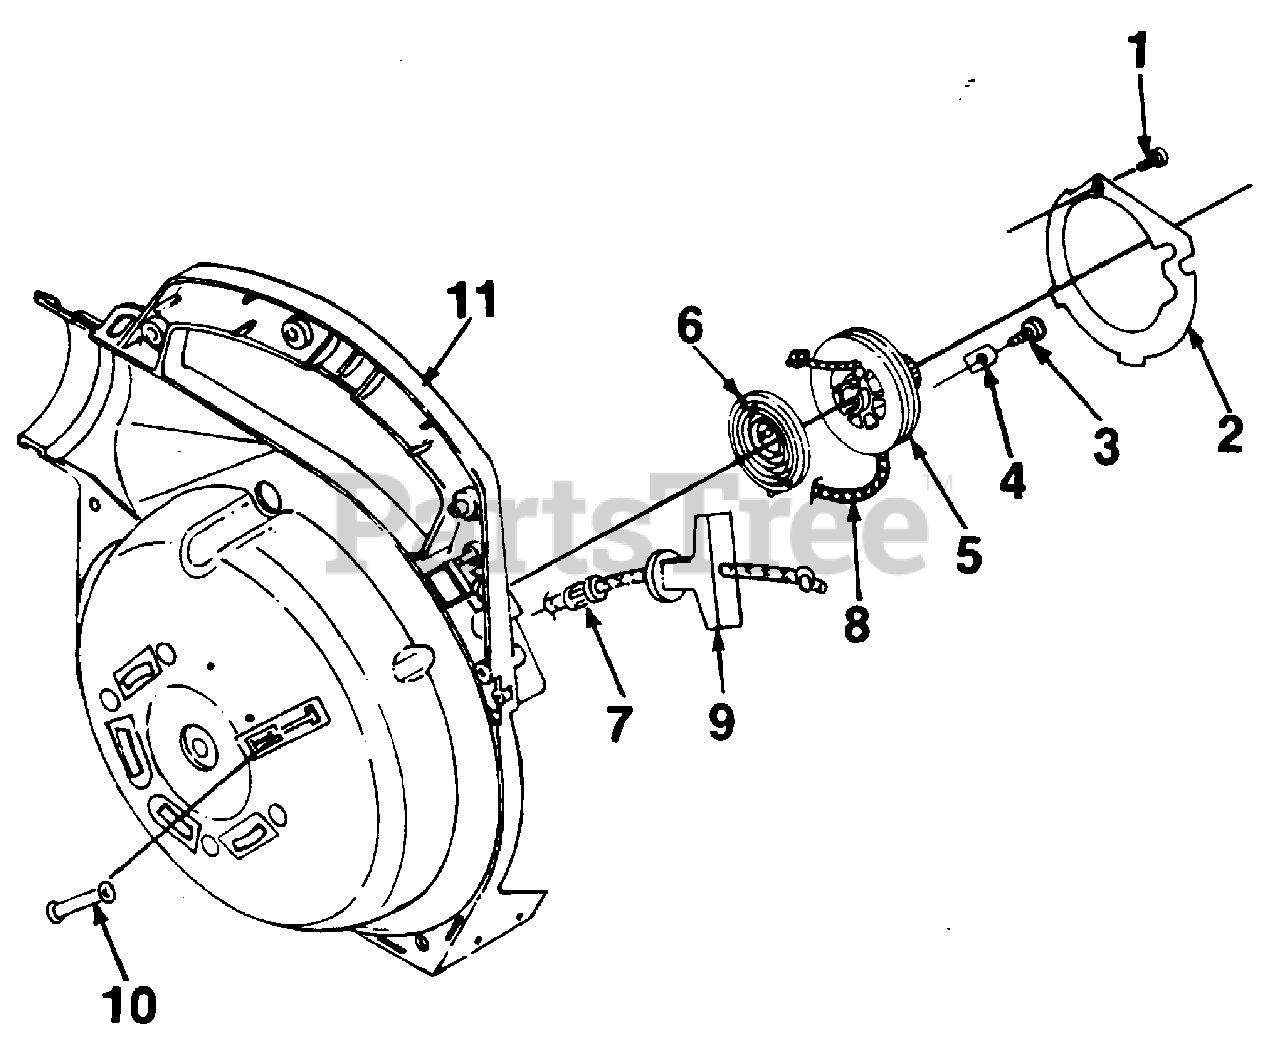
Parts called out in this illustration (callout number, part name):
1	SCREW- Thd. forming (#6-19 x 3/4")
2	PLATE- Rotor
3	SCREW- Thd. forming (10 x 1/2")
4	BRACKET- Retaining
5	PULLEY- Starter
6	SPRING & CONTAINER
7	BUSHING- Starter
8	ROPE- Starter 46"
9	GRIP- Starter rope
10	BUSHING- Starter rope
11	HOUSING-Volute (inner) w/decal
